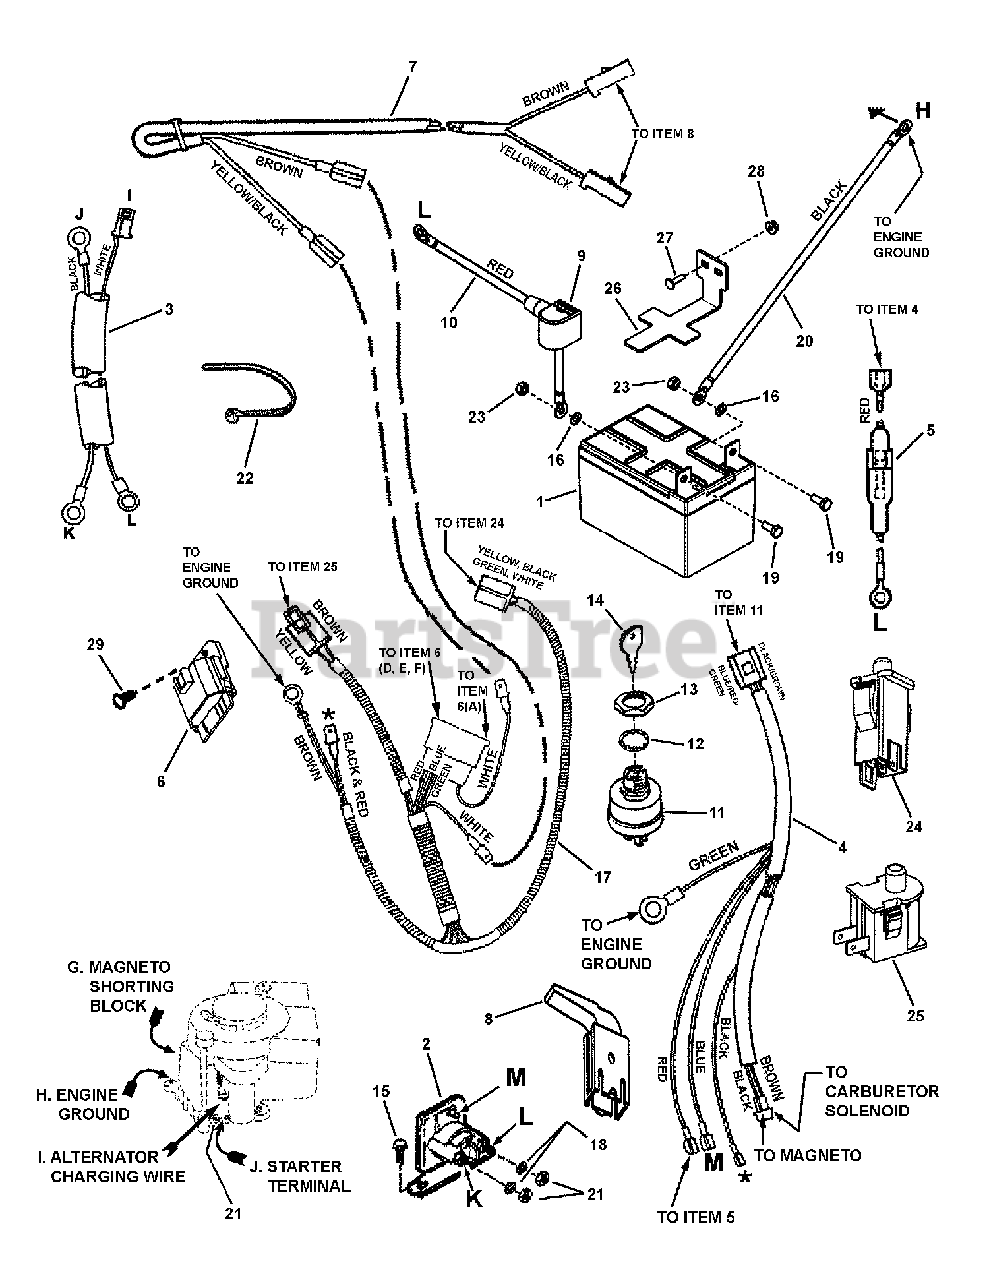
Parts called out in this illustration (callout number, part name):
1	BATTERY KIT, 12V 20HR: 190CCA
2	SOLENOID, Super Trombetta, RER
3	WIRE HARNESS, Starter
4	WIRE HARNESS, Key Switch, 14.5 B&S
5	HOLDER, Fuse
6	INTERLOCK MODULE, Briggs
7	HARNESS, (Deck Interlock Wiring)
8	SWITCH, Deck Interlock (NO)
9	BOOT, Insulator
10	WIRE, Positive, 17" Long
11	SWITCH, Ignition-Afterfire Solenoid
12	WASHER, 5/8" Internal Tooth Lock
13	NUT, 5/8-32 Hex
14	KEYS, BLISTER PK KIDS+MWRS DON'T MIX,DOM
15	SCREW, 1/4-20 x 1/2" Hex Washer Self-Tap
16	RETAINER, 1/4" Bolt, BP
17	WIRE HARNESS, B&S (13.5, 14.5 & 17.5)
18	WASHER, 1/4" Internal Tooth Lock
19	SCREW, 1/4-20 x 5/8 Hex Head Cap, GR 5, YZ
20	WIRE, Negative, 15" Long, Black
21	NUT, 1/4-20 Hex, GR 5 or B
22	CABLE TIE, 7"
23	NUT, 1/4-20 Hex Center Lock, GR 5 or B
24	SWITCH, Operator Presence Control (OPC) Traction (NC/NO)
25	SWITCH, Seat (NC)
26	BRACKET, Battery, RER
27	BOLT, #10-24 x 3/4, Round Head Square Neck Carriage, YZ
28	NUT, #10-24 Hex Flange Lock, BZ
29	FASTENER, 1/4" Ratchet
